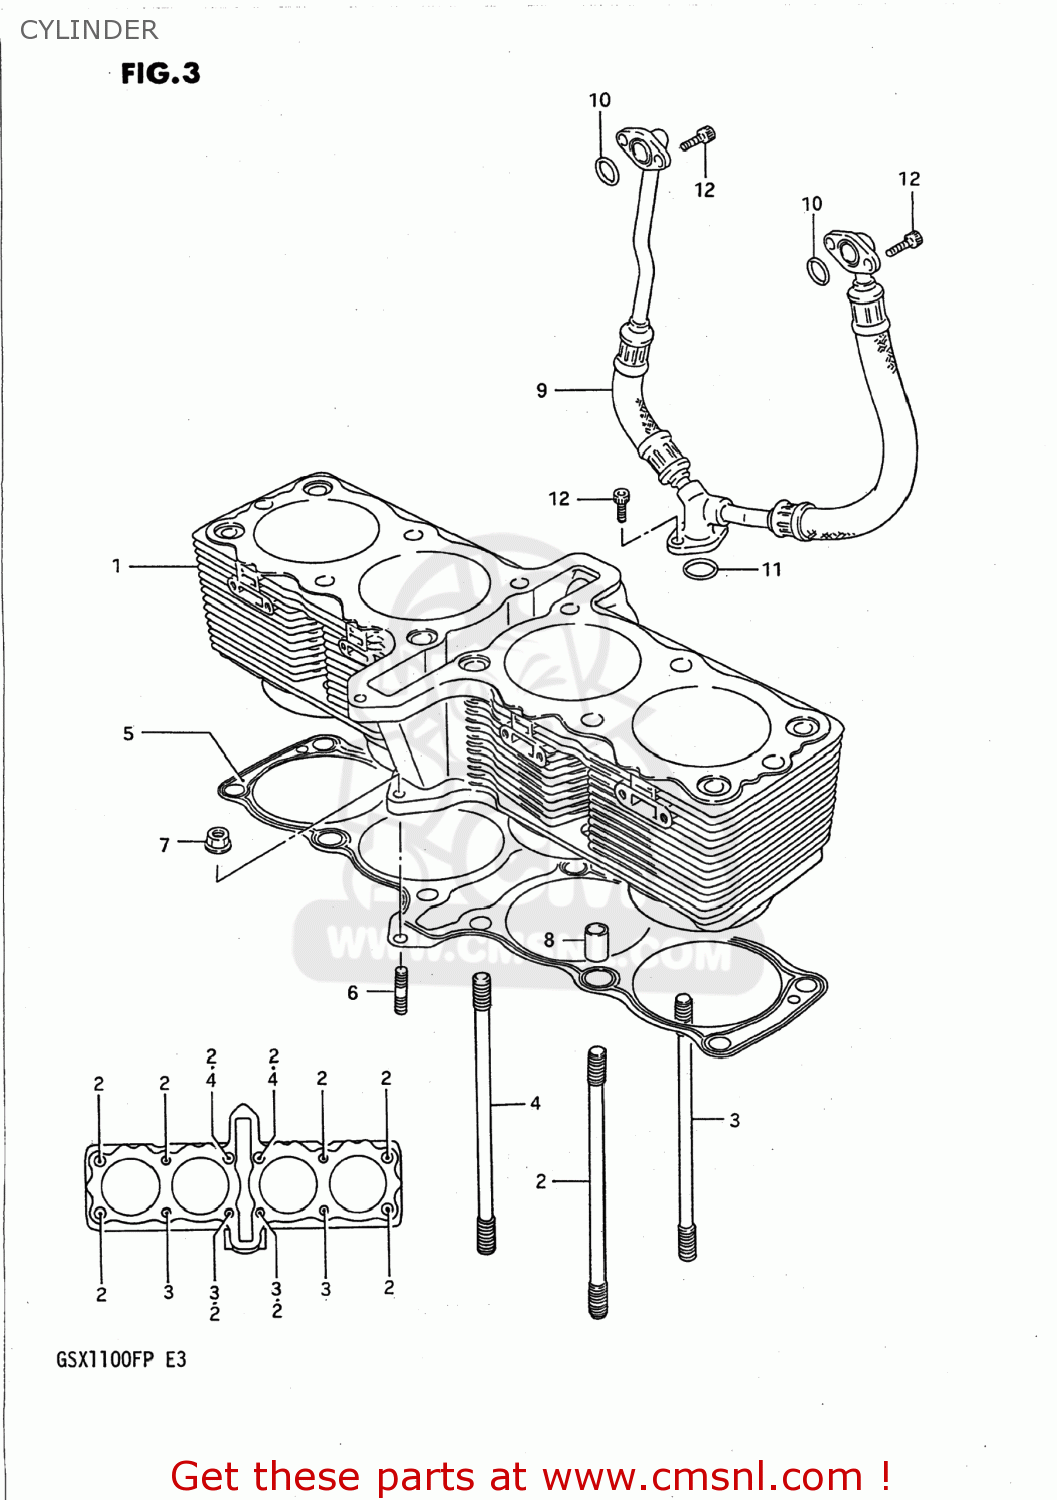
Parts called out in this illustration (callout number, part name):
1	CYLINDER
2	BOLT,STUD
3	BOLT,STUD
4	BOLT,STUD
5	GASKET,CYLINDER (NAS)
6	STUD BOLT L:20
7	NUT 6MM
8	PIN
9	HOSE
10	O RING(D:2.5,ID:13.8)
11	O RING(D:2.4,ID:15.8)
12	BOLT
